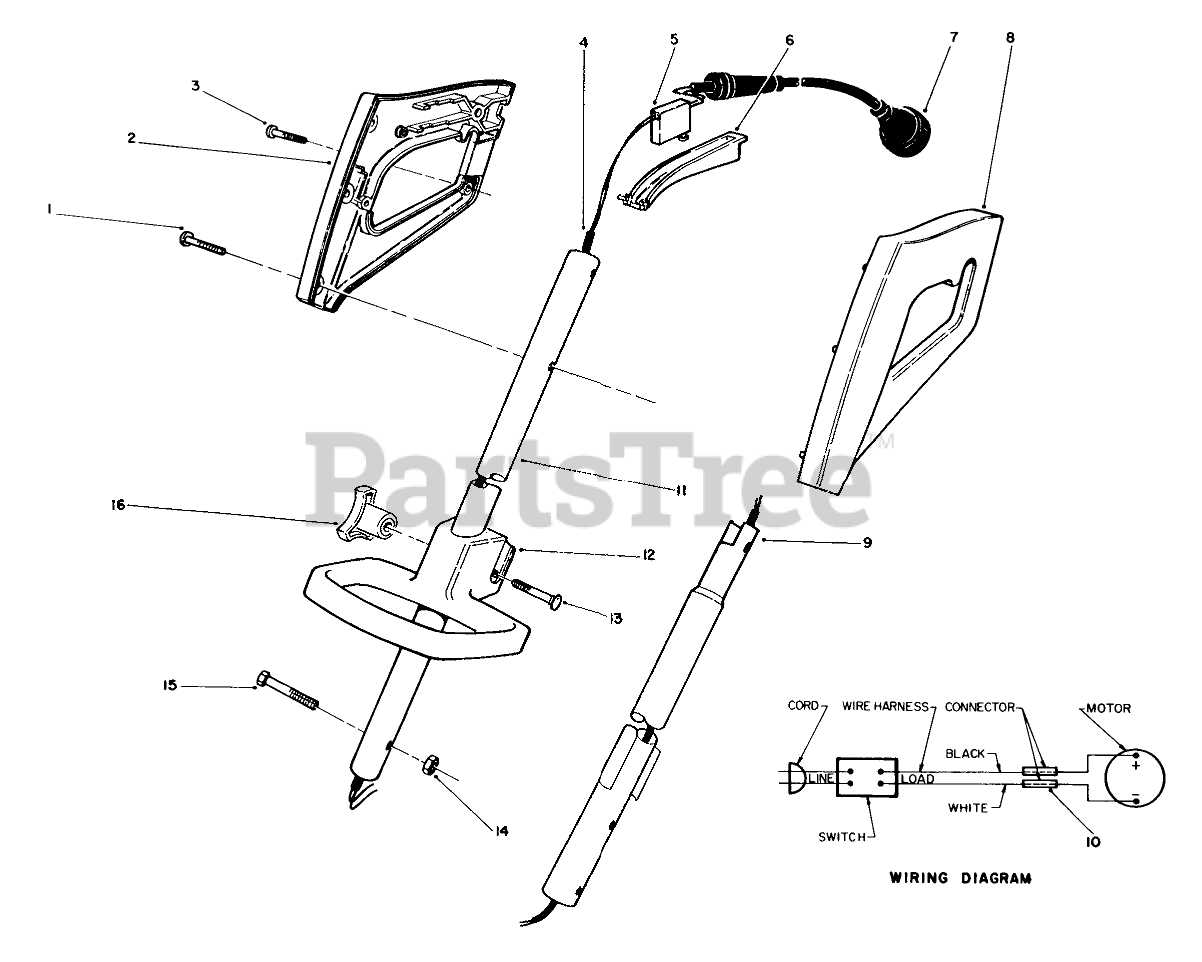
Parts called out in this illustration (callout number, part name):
1	Screw
2	HANDLE GRIP, RH
3	SCREW-PPH
4	WIRE HARNESS
5	SWITCH
6	TRIMMER-SWITCH BAR
7	Cord-Power
8	HANDLE GRIP, LH
9	TUBE-LOWER
10	CONNECTOR WIRE JOINT
11	Tube-Upper
12	Handle-Adjust
13	BOLT-CARR
14	NUT-LOCK, NI
15	HEX HD MACHINE SCREW
16	HANDLE KNOB
